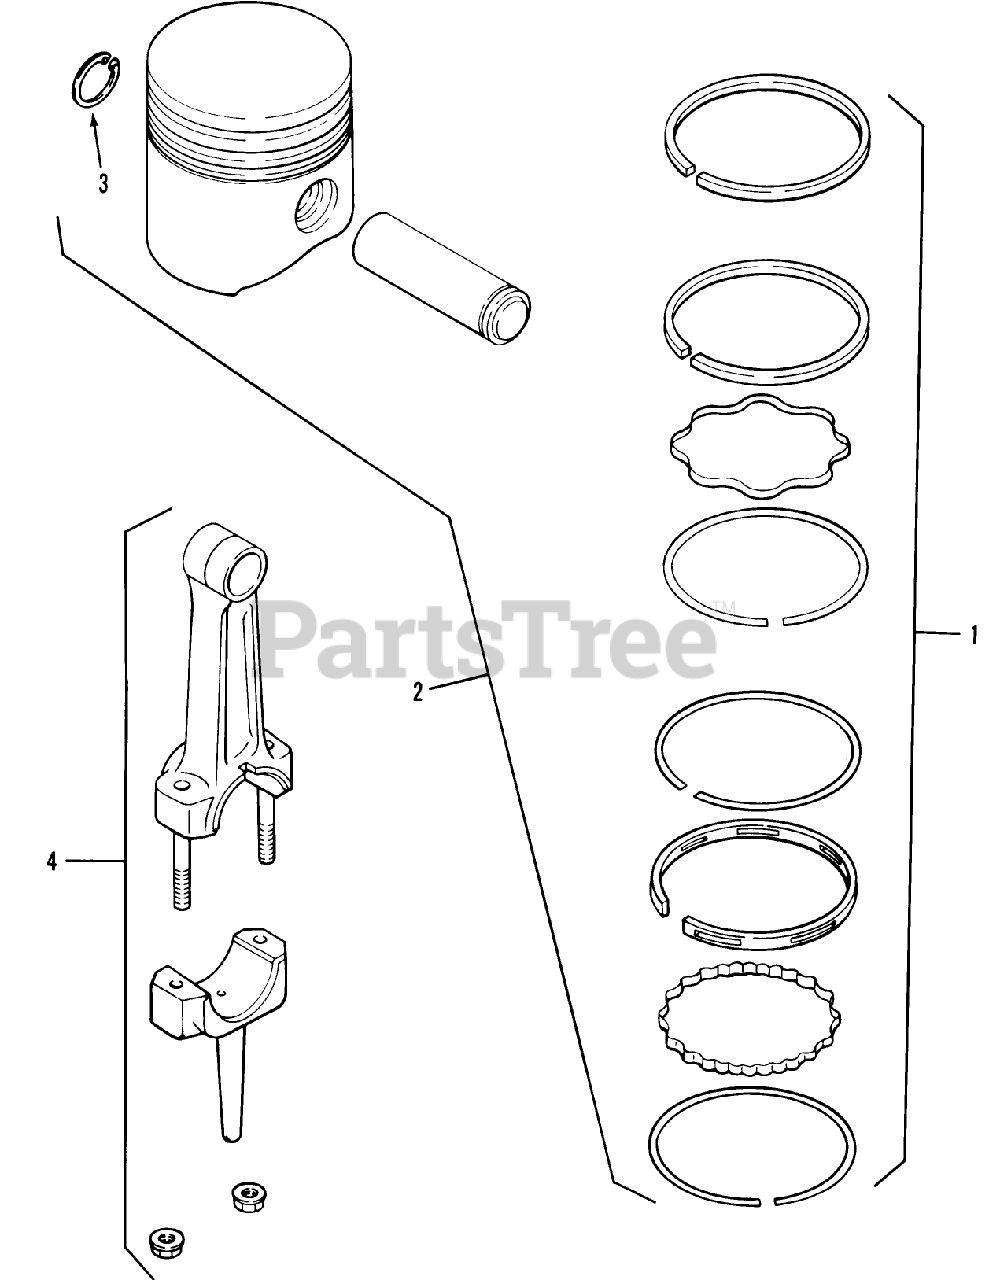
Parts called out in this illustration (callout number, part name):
1	KOHLER 235287
1	KOHLER 235288
1	KOHLER 235289
1	ORDER FROM KOHLER #235889
1	ORDER FROM KOHLER #235890
1	ORDER FROM KOHLER #235891
1	ORDER FROM KOHLER #235892
1	ORDER FROM KOHLER #236763
1	ORDER FROM KOHLER #236764
1	KOHLER # 236765
1	KOHLER # 236766
2	KOHLER 47-874.01
2	KOHLER 47-874-02
2	KOHLER 47-874-03
2	KOHLER 47-874-04
2	KOHLER 47-874-05
2	KOHLER 47-874-06
2	KOHLER 47-874-07
2	KOHLER 47-874-08
2	KOHLER 47-874-09
2	KOHLER 47-874-10
2	KOHLER 47-874-11
2	KOHLER 47-874-12
2	KOHLER 47-874-13
2	KOHLER 47-874-14
2	KOHLER 47-874-15
3	KOHLER 47-018-01
4	KOHLER 47-067-13
4	KOHLER 47-067-14
4	KOHLER 47-067-09
4	KOHLER 47-067-10
